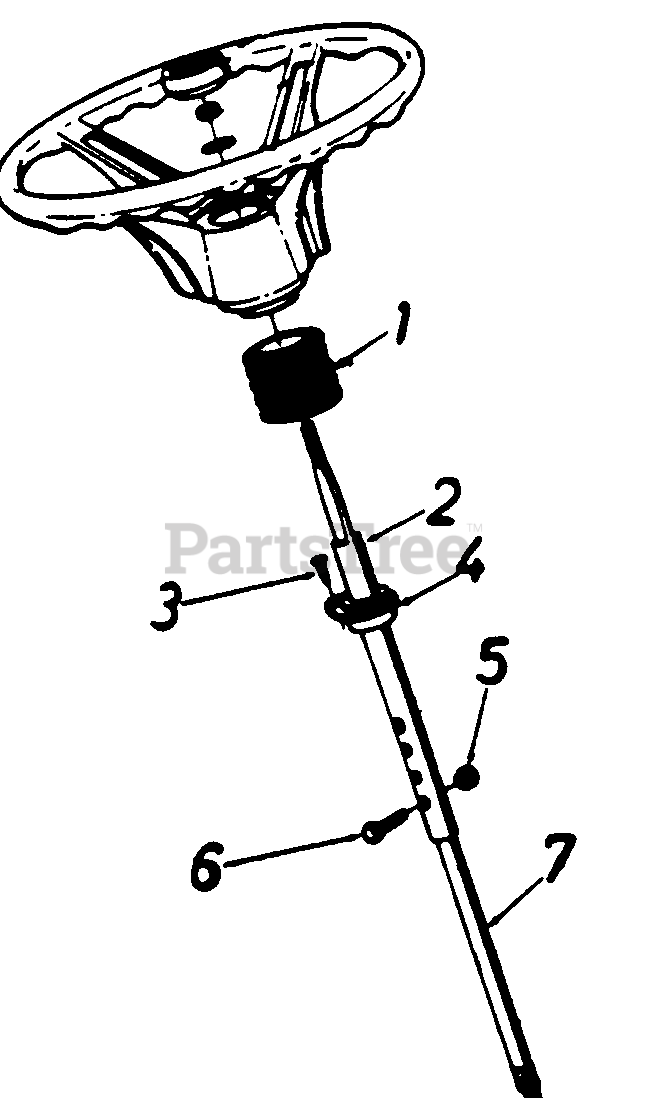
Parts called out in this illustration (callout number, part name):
1	Steering Bellow
2	Upper Steering Shaft
3	Oval Hd. C-Sunk Scr. #10 x 5/8" Lg.
4	Fl-Bearing .89" I.D. x 1.36" O.D.
5	Hex L-Nut 1/4-20 Thd.
6	Hex Bolt 1/4-20 x 1.31" Lg.
7	Lower Steering Shaft
